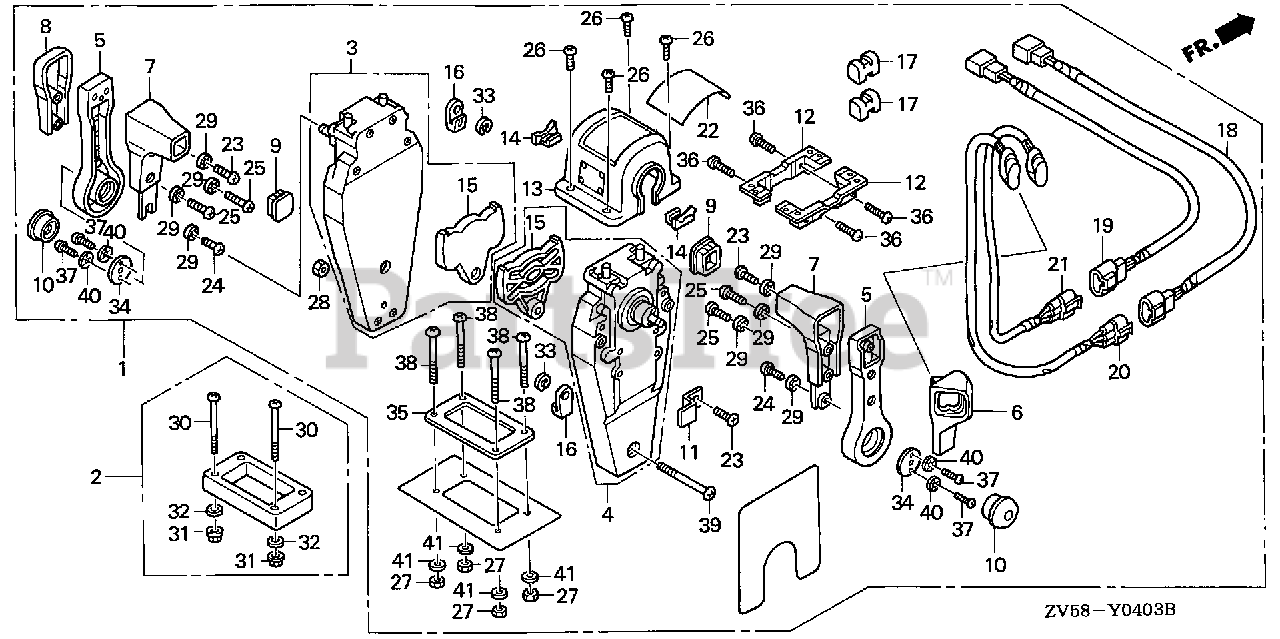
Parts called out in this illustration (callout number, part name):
1	BOX KIT, REMOTE CONTROL (TOP MOUNT DUAL)(L)
2	SPACER KIT, REMOTE CONTROL BOX (TOP MOUNT DUAL)
3	HOUSING ASSY., L. (INNER) (TOP MOUNT)
4	HOUSING ASSY., R. (INNER) (TOP MOUNT)
5	HANDLE, REMOTE CONTROL
6	COVER, R. GRIP
7	GRIP, REMOTE CONTROL HANDLE
8	COVER, DUAL GRIP
9	CAP, GRIP
10	BUTTON, THROTTLE
11	PLATE, CABLE CLAMP
12	BRACKET, REMOTE CONTROL HOUSING
13	HOUSING, DUAL REMOTE CONTROL BOX
14	HOUSING, LEAD
15	PLATE, DWELL
16	TERMINAL, CABLE
17	SPACER, CABLE CLAMP
18	SUB-HARNESS ASSY., POWER TRIM-TILT (A)
19	SUB-HARNESS ASSY., POWER TRIM-TILT (B)
20	SWITCH ASSY., POWER TRIM-TILT (A)
21	SWITCH ASSY., POWER TRIM-TILT (B)
22	MARK, REMOTE CONTROL (DUAL)
23	SCREW, PAN (5X16)
24	SCREW, PAN (5X10)
25	SCREW, PAN (5X20)
26	SCREW, PAN (4X10)
27	NUT, HEX. (5MM)
28	NUT, HEX. (5MM)
29	WASHER, LOCK (5MM)
30	SCREW, PAN (5X65)
31	NUT, FLANGE (5MM)
32	WASHER, PLAIN (5MM)
33	E-RING (6MM)
34	PLATE, HANDLE
35	GASKET, DUAL
36	SCREW, PAN (5X18)
37	SCREW, PAN (6X18)
38	SCREW, PAN (5X40)
39	SCREW, PAN (5X55)
40	WASHER, LOCK (6MM)
41	WASHER, PLAIN (5MM)
